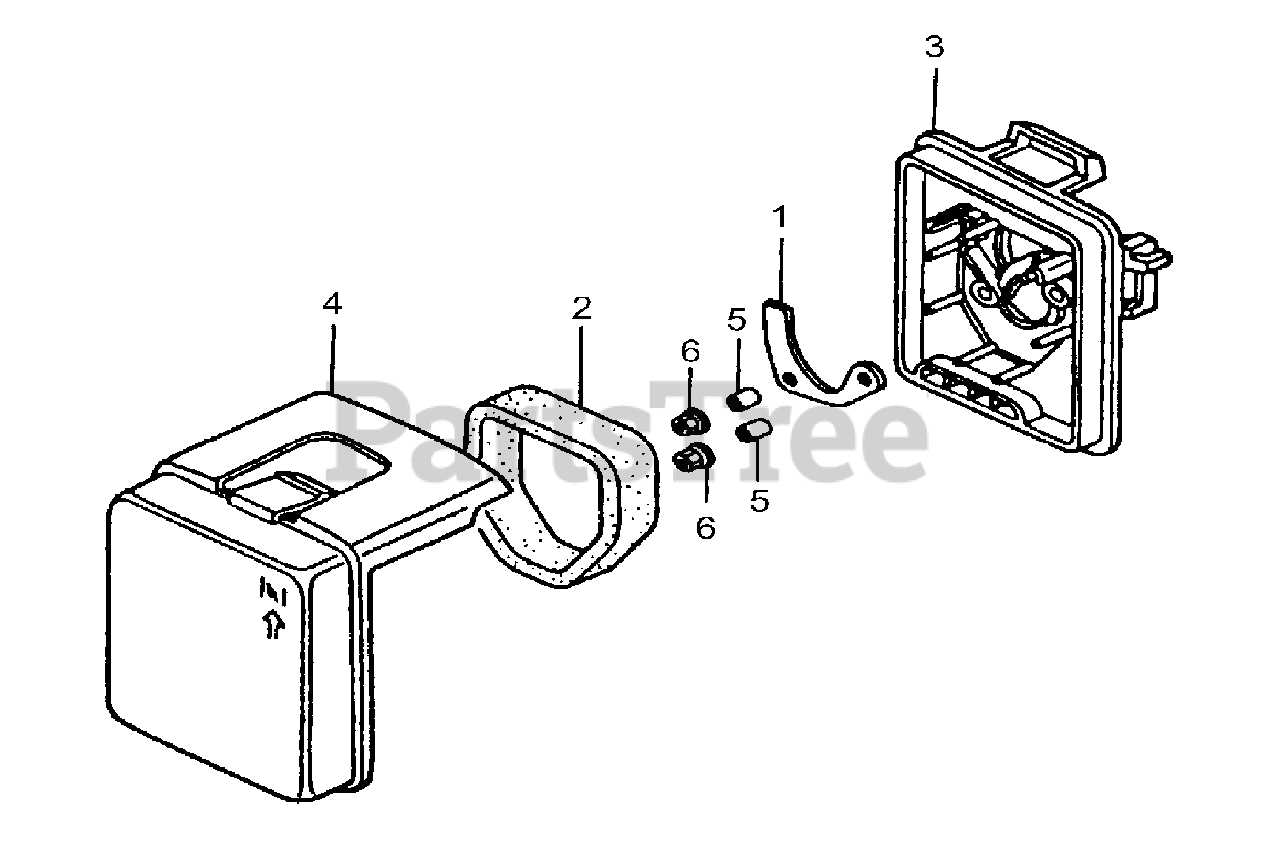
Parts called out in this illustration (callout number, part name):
1	PLATE, OIL TRAP
2	ELEMENT, AIR CLEANER
3	HOUSING COMP., AIR CLEANER *R8*
4	COVER, AIR CLEANER *R8* (BRIGHT RED)
5	COLLAR, AIR CLEANER
6	NUT, FLANGE (5MM)
